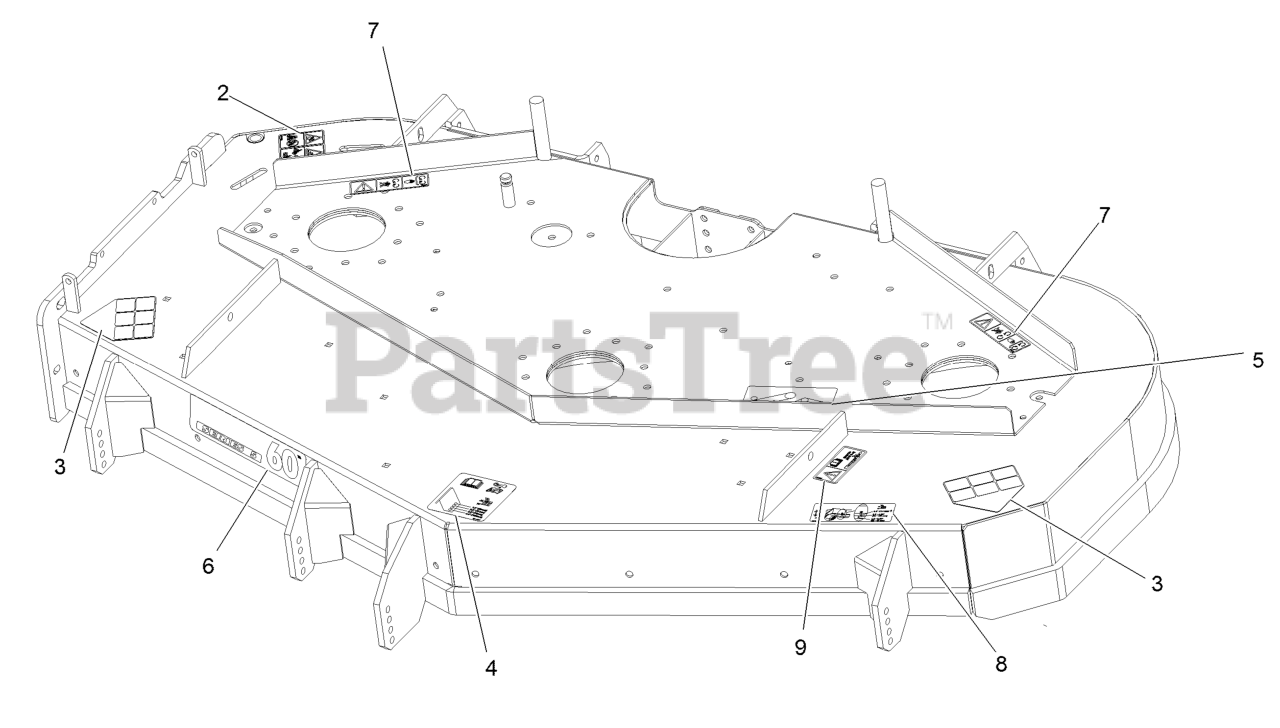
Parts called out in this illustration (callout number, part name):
2	DECAL-DANGER
3	DECAL-DANGER
4	DECAL-HEIGHT OF CUT
5	DECAL-BELT ROUTING
6	DECAL, SERIES 5 - 60
7	DECAL-COVER, MISSING
8	DECAL-BAFFLE ADJ
9	DECAL-BOLT TORQUE
